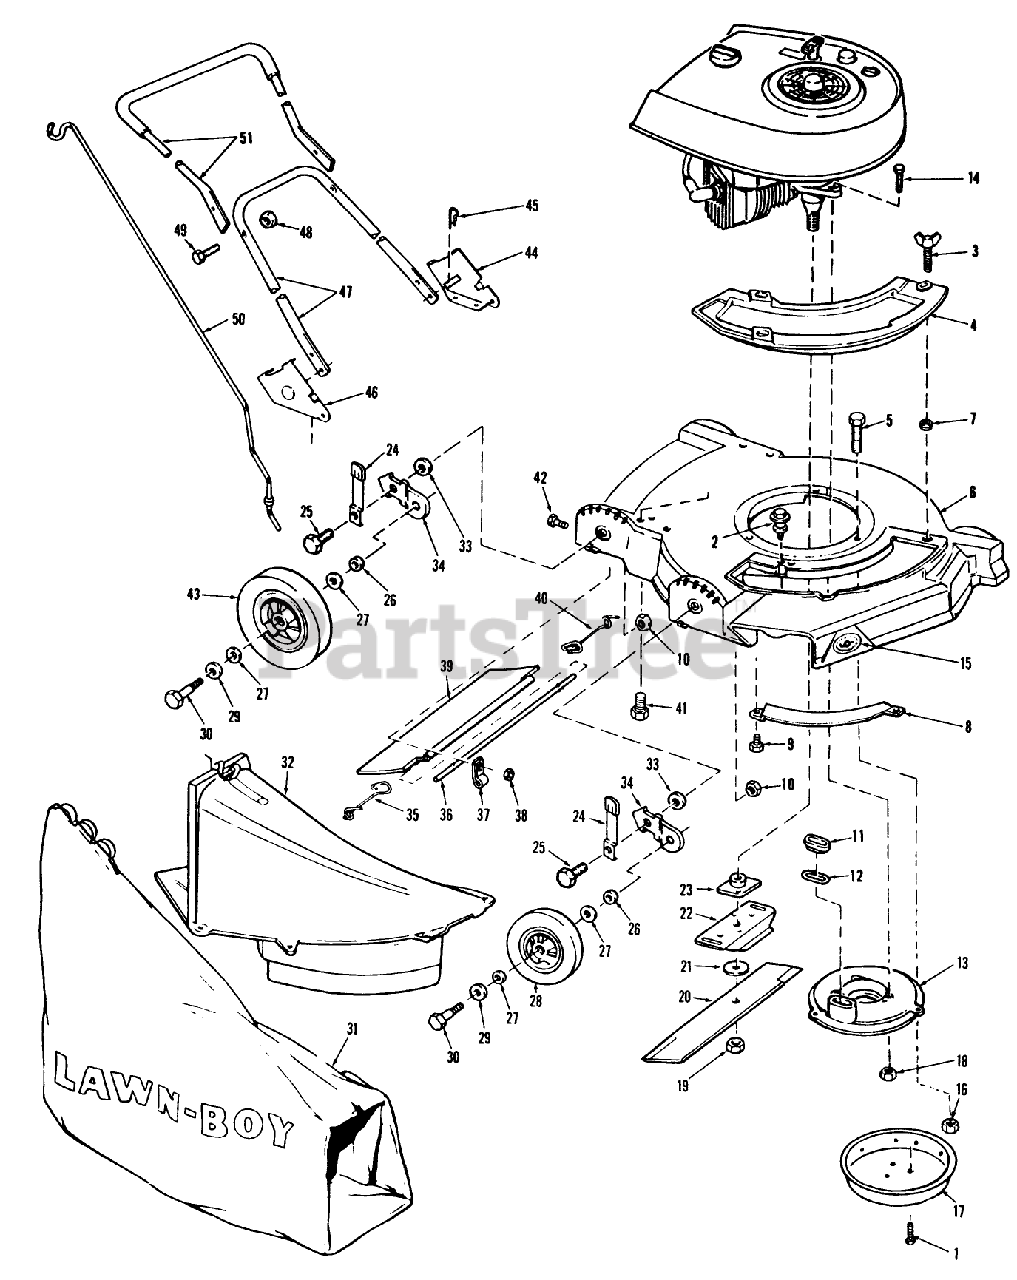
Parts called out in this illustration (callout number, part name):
3	WING SCREW LAWRE
5	SCREW V
8	TOE BAR 19"
8	BAR-TOE
10	LOCKNUT
12	GASKET S
16	NUT-LOCK F
18	NUT-LOCK F
19	NUT-BLADE
21	WASHER
23	PLATE AND COLLAR ASM
26	WASHER WROUGHT
30	BOLT WHEEL
35	SPRING;TRAILING SHIELD RH
36	ROD T/SHIELD ADV WIRE
36	ROD 21" ADVANCE
37	CLAMP ROD KMC
38	LOCKNUT E
39	TRAILING SHIELD-19
39	SHIELD
40	SPRIG T/SHLD ASOC
45	HAIR PIN
47	Cover Plate
48	LOCKNUT E
50	ROD GRASSBAG
51	Handle and Grip Assembly-Top
